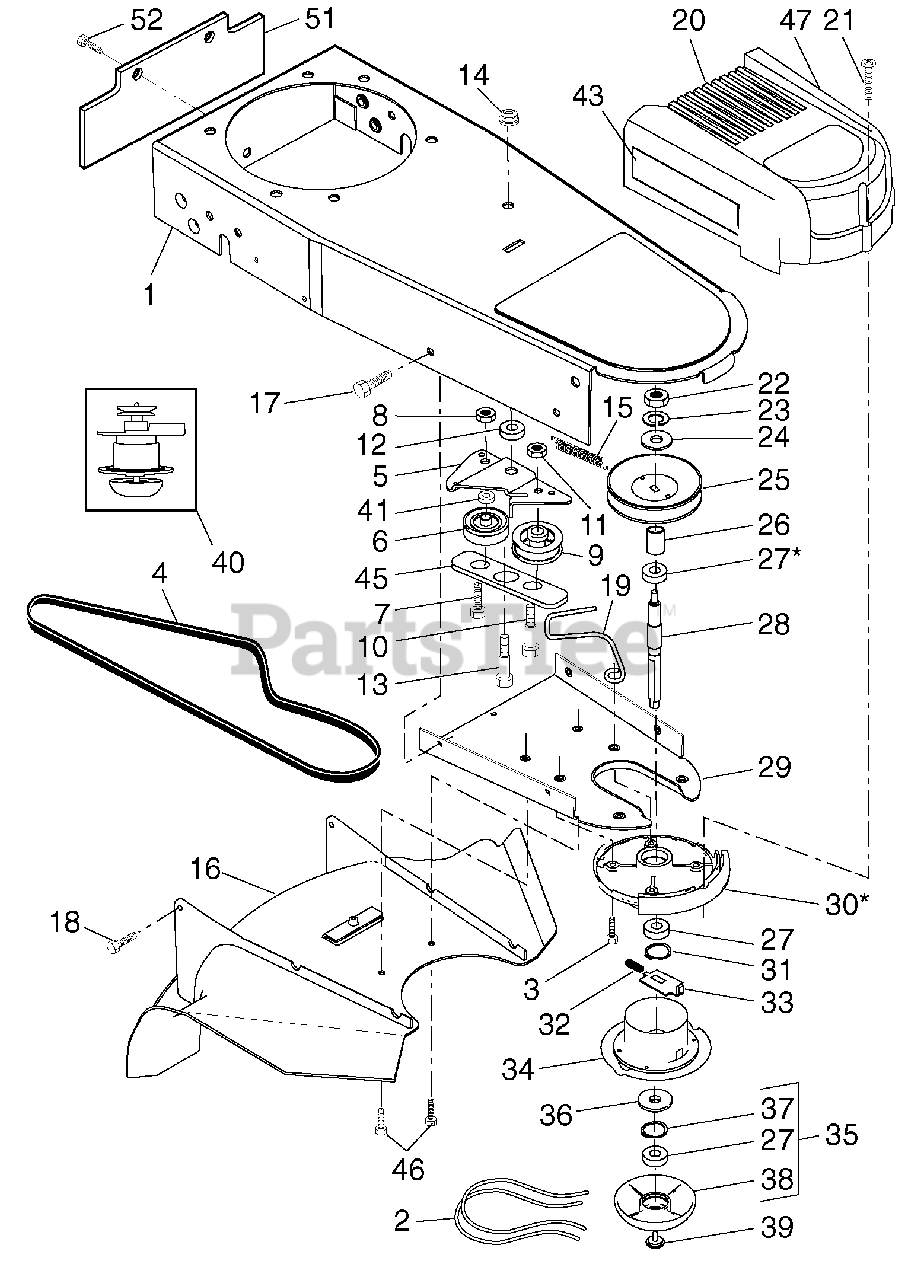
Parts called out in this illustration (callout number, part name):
1	Chassis Assembly
2	Line, Trimmer .155 diameter x 18.75 long
3	Screw, Self-Tapping 5/16-18 x 1
4	V-Belt
5	Bracket, Idler
6	Pulley, Idler, V-Groove
7	Bolt, Hex Head 3/8-16 x 1.25
8	Locknut, Hex 3/8-16
9	Pulley, Idler, Flat
10	Bolt, Shoulder
11	Locknut, Hex 5/16-18
12	Spacer
13	Bolt, Shoulder
14	Locknut, Flange
15	Spring, Return
16	Deflector, Bottom
17	Screw 1/4-20 x 1/2
18	Screw #10-24 x 3/4
19	Belt Keeper
20	Cover, Chassis, Top
21	Screw #10-24 x 1-3/4
22	Nut, Hex 3/8-24 UNF
23	Washer, Lock 3/8
24	Washer, Flat 3/8
25	Pulley, Driven
26	Spacer, Pulley
27	Bearing
28	Jackshaft
29	Cover, Chassis, Bottom
30	Spindle Housing Assembly
31	Ring, Retaining, External, 17mm
32	Spring, Locking Plate
33	Locking Plate
34	Carrier Plate Assembly
35	Mow Ball Assembly
36	Cover, Bearing
37	Ring, Retaining, Internal, 40mm
38	Mow Ball
39	Bolt, Mow Ball
40	Spindle Assembly, Complete
41	Spacer
43	Decal, Instruction
45	Belt Keeper, Bottom
46	Screw, Self-Tapping
47	Decal, Instruction
51	Deflector, Rear
52	Screw
